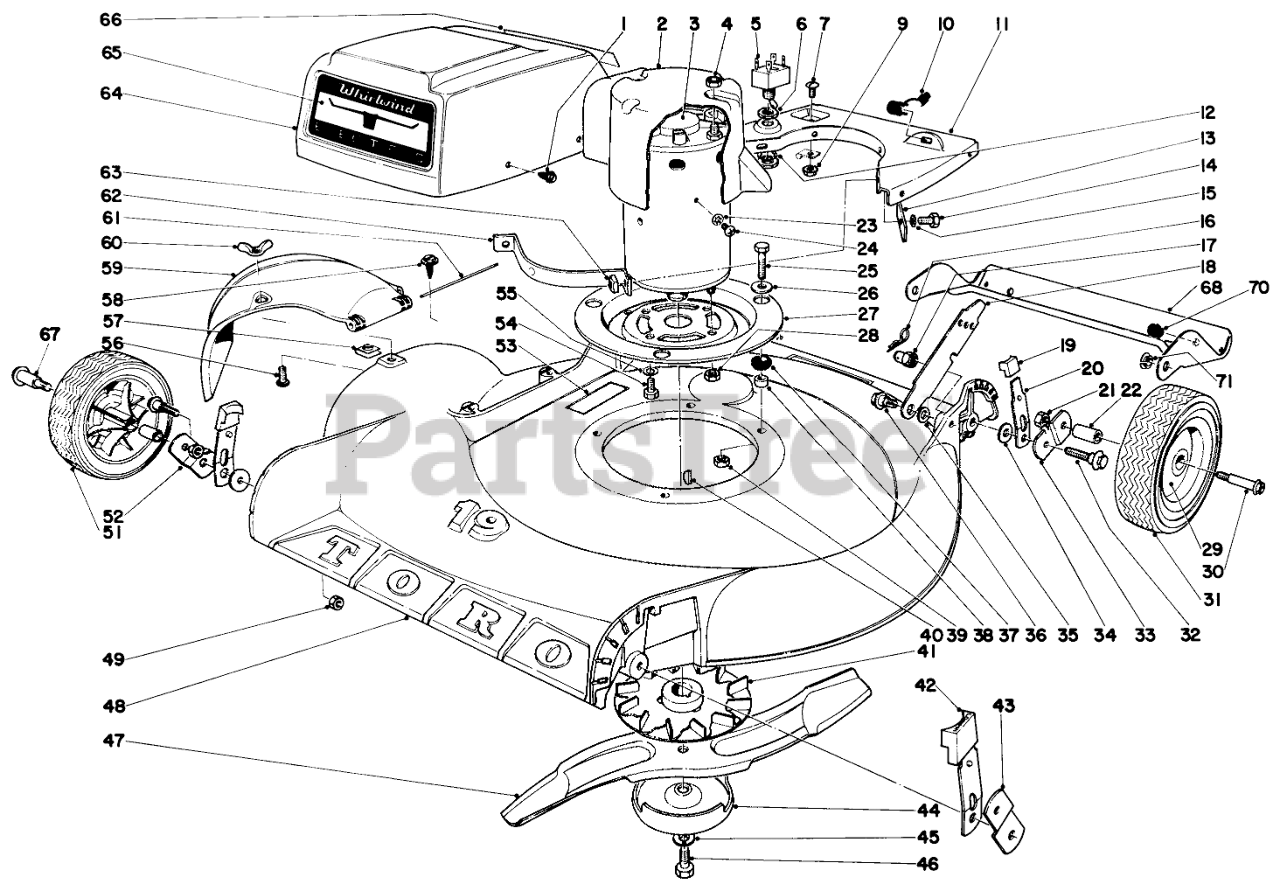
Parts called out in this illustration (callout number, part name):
1	SCREW-HWHTF
2	Cover-Switch & Motor
3	Motor
5	Switch
7	10-24 X 5/8 PAN HD MS
9	NUT-KEPS
10	Strain Relief
11	Support Shroud
12	Lockwasher
13	Washer Support
14	SCREW-HH
15	WASHER-LOCK/EXT
16	PIN-COTTER, HAIR
17	Nut
18	Latch
20	Spring Arm
21	Nut
22	Bushing
23	WASHER-LOCK/INT
25	SCREW-HH
26	WASHER-FLAT
27	Motor Support Plate
28	Nut
29	Wheel Assy. (Incl. Ref. No. 22)
30	Wheel Bolt
31	8 TIRE
32	Pivot Screw
33	Pivot Arm
34	WASHER-PIVOT
35	SPACER
36	SCREW-SHOULDER
37	GROMMET
38	Spacer
39	Nut
40	KEY-WOODRUFF
41	Fan & Blade Retainer
42	ARM KNOB
43	Pivot Arm
44	Cup-Anti Scalp
45	WASHER-LOCK
46	SPECIAL SCREW
47	Blade
48	Housing
49	Nut
52	Pivot Arm
53	Decal
54	SCREW-HH
55	WASHER-LOCK, INTERNAL
57	NUT-SPEED
58	SCREW-HWHTF
59	Deflector
60	NUT-WING SPECL
61	HINGE PIN
62	Clamp-Shroud Support
63	NUT-SQUARE
64	Shroud
65	Decal-Whirlwind
66	Decal
66	Decal (Canadian)
68	REAR SAFETY SHIELD
70	SKID BUTTON
71	Nyliner
